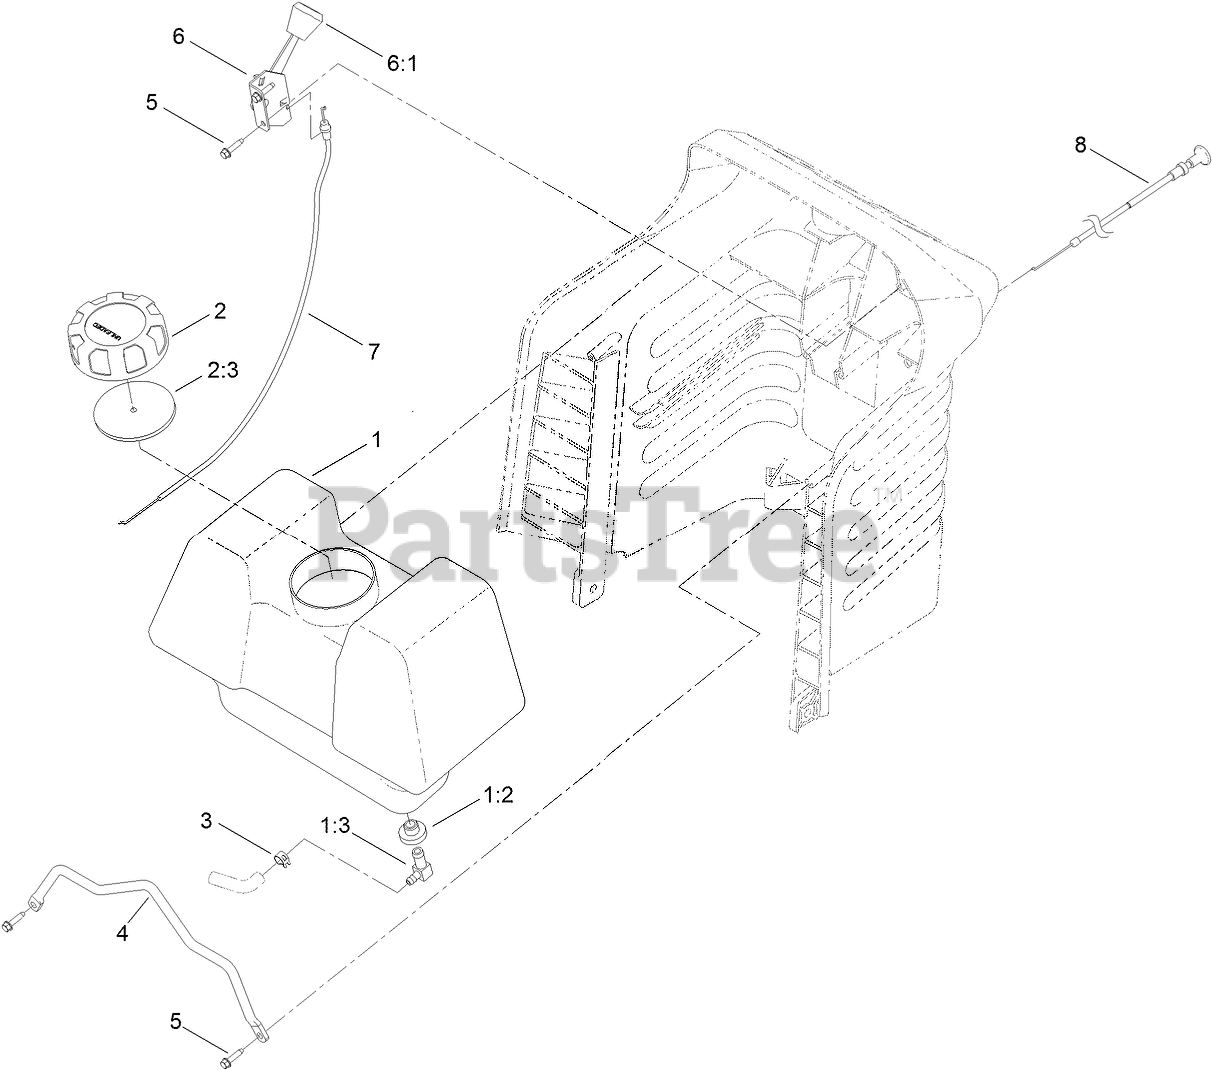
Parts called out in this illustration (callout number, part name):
1	GAS TANK ASM
1:2	BUSHING
1:3	VALVE-FUEL
2	GAS CAP ASM
2:3	GASKET-CAP, GAS
3	CLAMP-HOSE
4	ROD-TANK, GAS
5	SCREW-SPECIAL
6	THROTTLE CONTROL ASM
7	CABLE-THROTTLE
8	CHOKE CONTROL ASM
